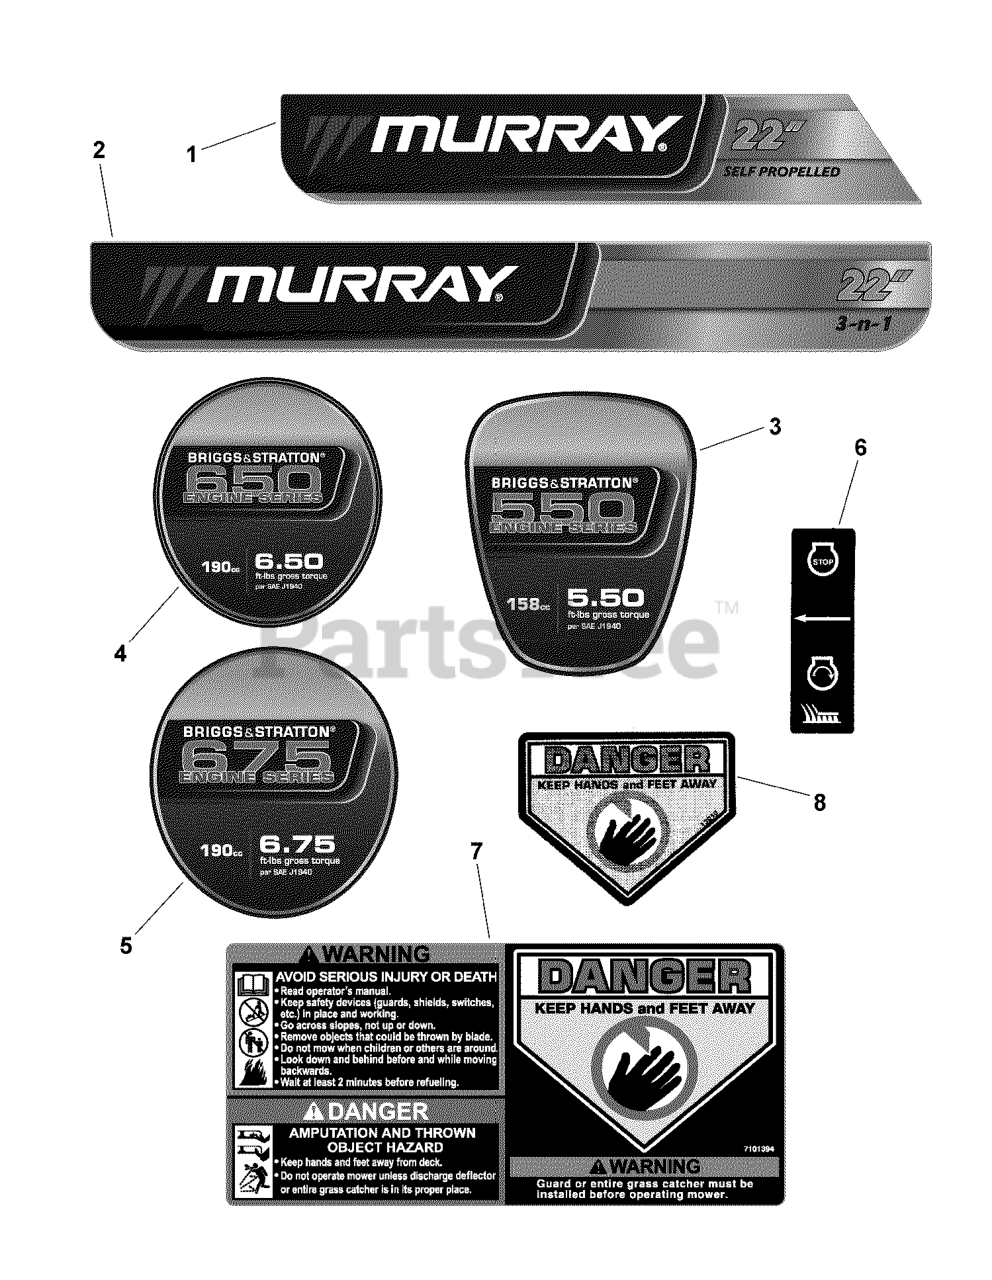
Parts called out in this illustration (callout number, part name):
1	DECAL, Murray Logo, Deck
2	DECAL, Murray Logo, Deck
3	DECAL, Engine, Murray, TP, 550
4	DECAL, Engine, Murray, TP, 650
5	DECAL, Engine, Murray, TP, 675
6	DECAL, OPC Bail International Symbol
7	DECAL, Warning, Rear Discharge Door
8	DECAL, Danger, Cut Finger
